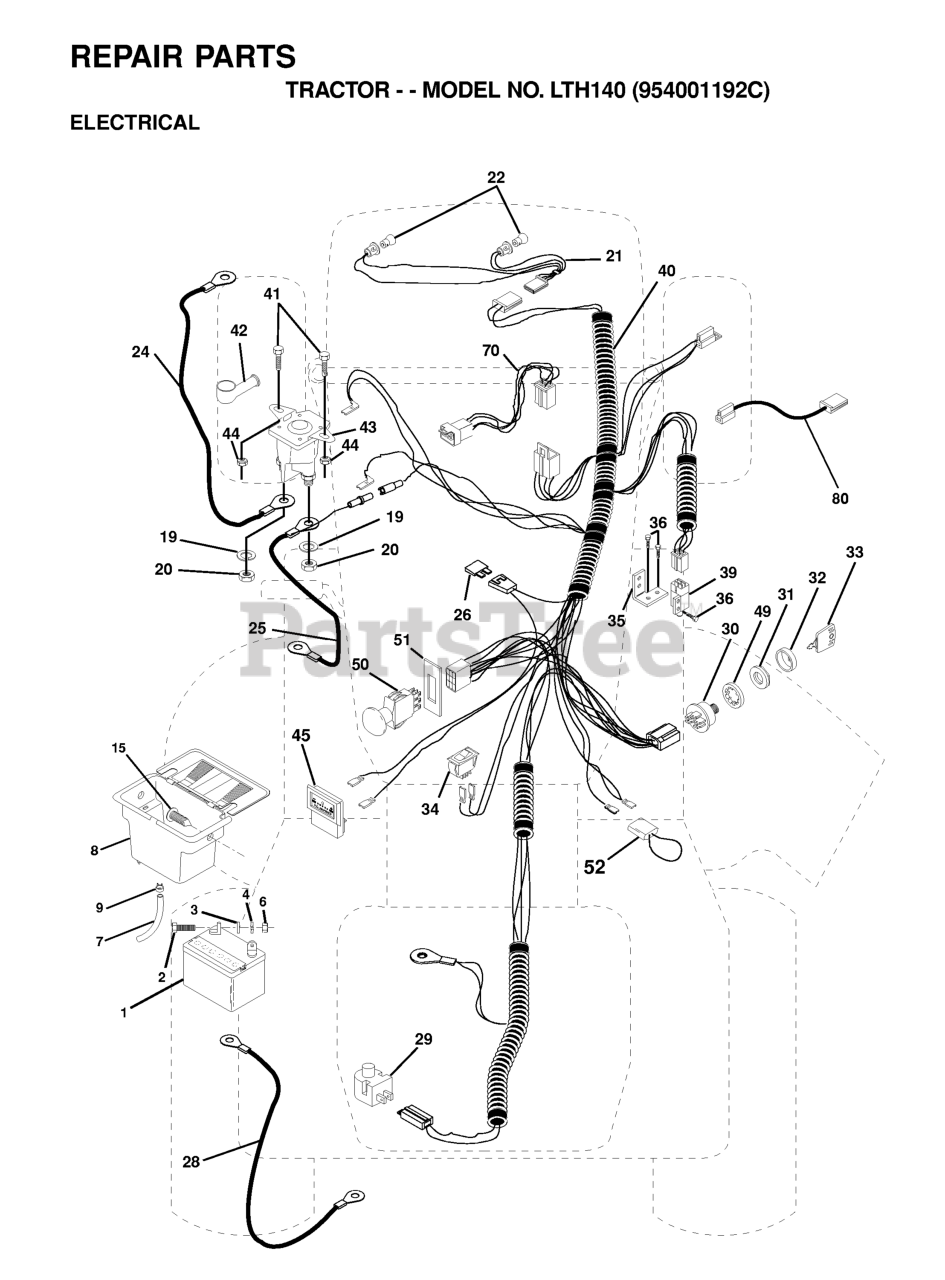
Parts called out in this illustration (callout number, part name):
1	BATTERY
2	BOLT.HEX.1/4.X.3/4.DICHROMATE
4	LOCKWASHER
6	NUT
7	TUBE BATTERY DRAIN
8	BATTERY CASE
9	HOSE CLAMP T
15	FASTERER SNAP-IN
19	LOCKWASHER
20	NUT
21	HARNESS LIGHT SOCKET
24	CABLE.BATTERY.6GA.RD
28	CABLE T
29	RP.SWITCH.PLUNGER.NC.GRAY
30	IGNITION SWITCH
31	NUT, IGNITION
32	COVER SWITCH KEY
33	KEY MLD GEN DELTA
35	BRACKET LT
39	SWITCH INTERLOCKT
40	HARNESS IGN ELECT
41	BOLT
42	TERMINAL COVER
43	SOLINOID
44	Nut, Keps Blk Hex 1/4-20 UNC
45	AMMETER
49	Washer, Lock Internal Tooth 5/8
50	SWITCH-PTO
51	FRAME RETAINING RING
52	WIRE PROTECTION LOOP
70	HARNESS ENG. KOHLER
80	HARNESS, CLUTCH
